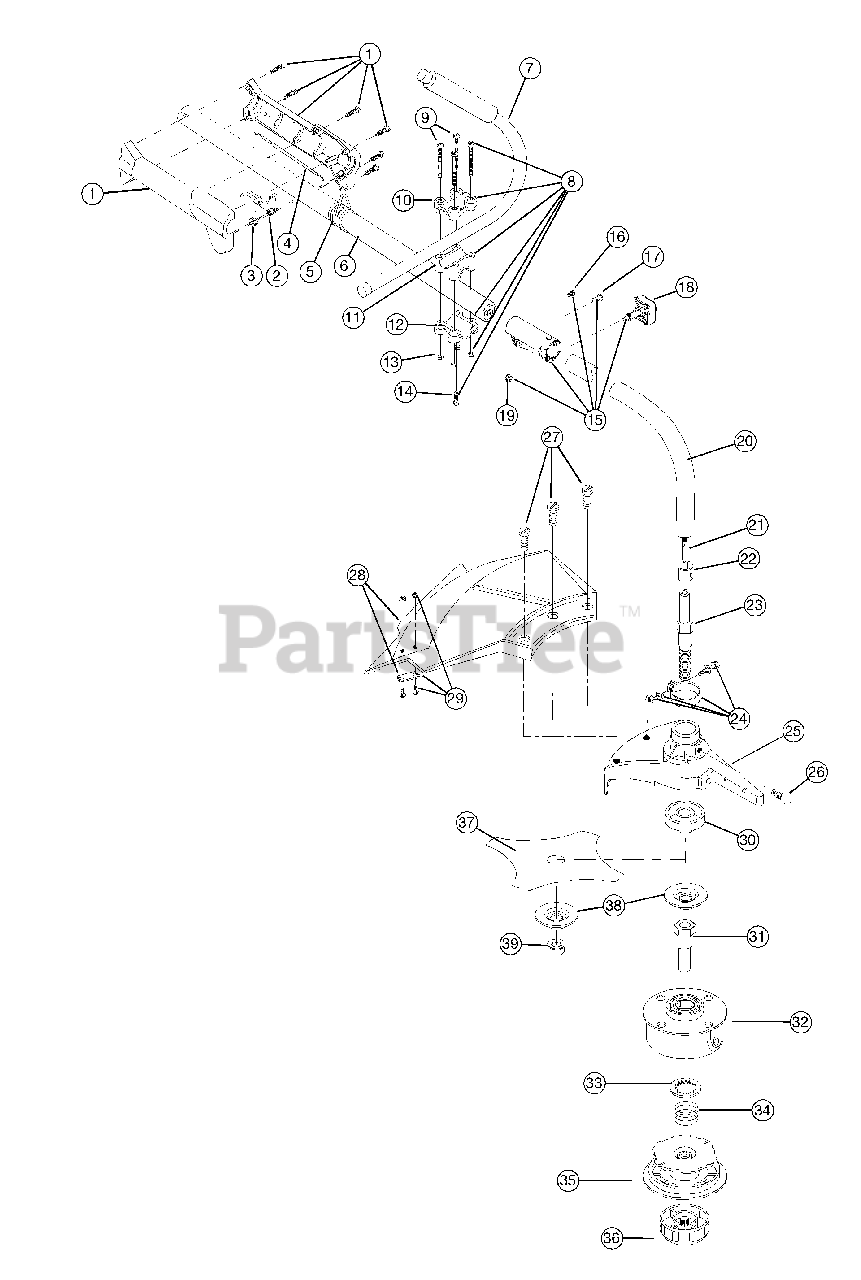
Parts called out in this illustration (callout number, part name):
1	Throttle Housing & Trigger Assembly
2	Throttle Trigger
3	Throttle Trigger Spring
4	Throttle Cable Assembly
5	Harness Clip
6	Upper Drive Shaft Housing Assembly
7	J-Handle Assembly
8	Handle Bracket Assembly
10	Upper Handle Clamp
11	Middle Handle Clamp
12	Lower Handle Clamp
14	Anti-Rotation Screw
15	EZ-Link Coupler
18	Adjustment Knob
19	Knob Retaining Nut
20	Lower Drive Shaft Housing Assembly
21	Lower Flexible Drive Shaft
22	Retainer Sleeve
23	Output Shaft
24	Clamp Assembly
25	Bearing Housing Assembly
26	Mounting Bolt
27	Shield Mounting Screw
28	Shield and Blade Assembly
29	Blade Assembly
30	Shaft Bushing
31	Spool Shaft
32	Outer Spool
33	Retainer
35	Inner Reel
36	Bump Head Knob Assembly
37	4-Tooth Blade
48	Retaining Washer
